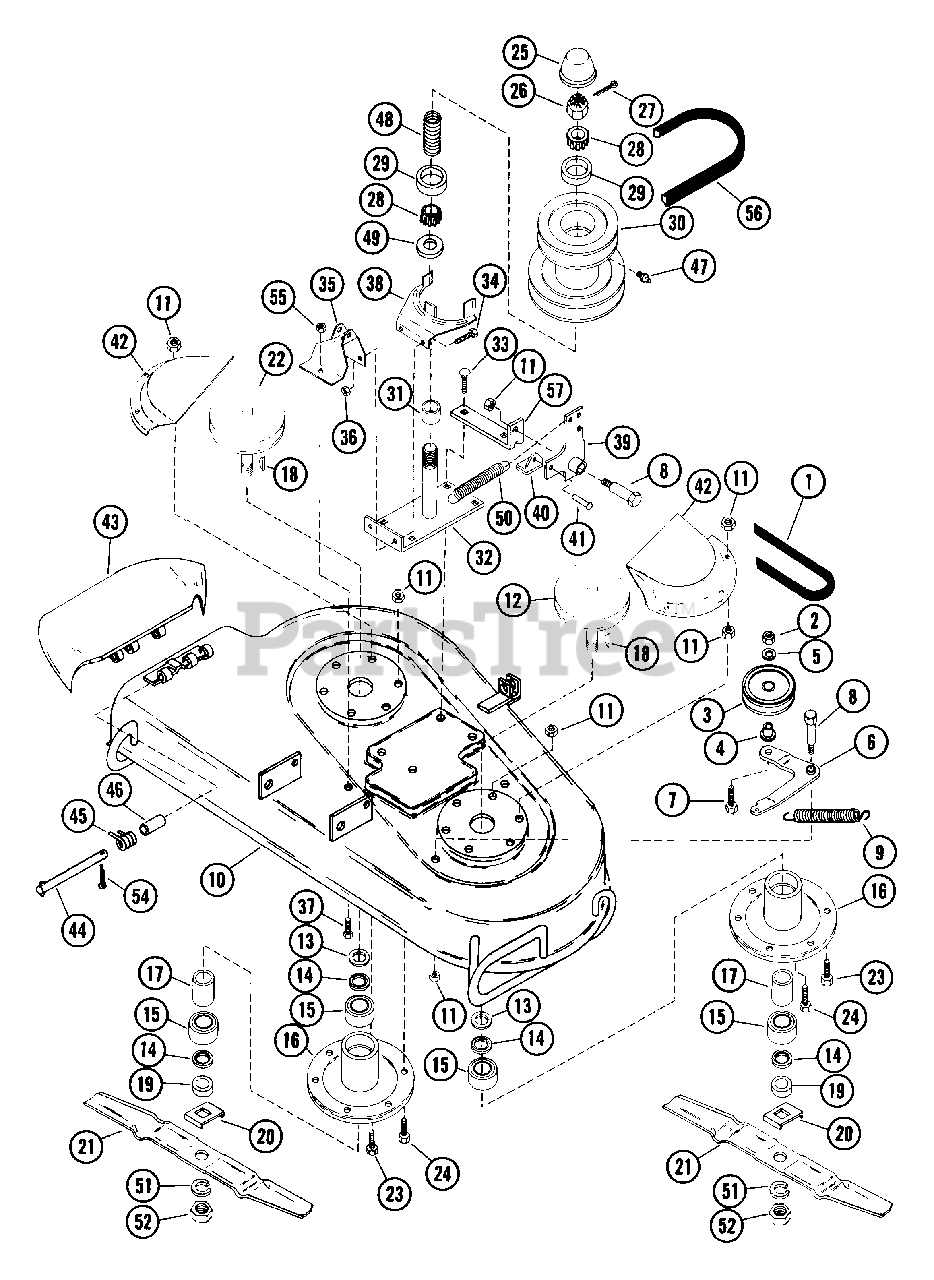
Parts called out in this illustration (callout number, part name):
1	V-BELT, 4L-RAW EDGE
2	NUT-LK-CTR .50-13
3	IDLER-FLAT 2.75X.62
4	BSHG-FLG .500X.625X.500X.750
5	WSHR-FL-STL .505X.880X.072 PL
7	BLT-HEX .50-13X1.25 PL GR2
8	SHOULDER BOLT
9	SG-TENS .091X.73X5.28 WLD 30
10	PAN ASSEMBLY
11	NUT-LK-CTR .375-16 GR A PL
13	WSHR-FL-STL .755X1.250X.125
14	BEARING SLINGER
15	BRG-BALL .751X1.78X.61
16	SPINDLE HOUSING
17	SPACER .753X1.000X1.140
18	KEY-WDRF .188X.75X.313 SAE 9
19	RETAINER HUB
20	BLADE TRAY
21	MOWER BLADE
22	SHEAVE
23	BLT-HEX .38-16X1.00 PL
24	BLT-HEX .38-16X.75 PL GR2
25	CAP, GREASE
26	NUT-JAM SL .75-20 PL
27	PIN-COTR .12 X 1.25 PL
28	BRG-CONE .750X.61
29	BRG-CUP 1.781X.475
30	SHEAVE ASSEMBLY-MOWER
31	SPACER .753X1.000X.625
33	BLT-RDHDSQNK .38-16X.75 SHT PL
34	BLT-SERHFWH .31-18X.75 PL
35	BRACKET
36	NUT-FLG. .312-18 PL
37	BLT-HEX .31-18X.50 PL GR2
41	RVT .25X.50 RH ST
43	PAN CHUTE EXTENSION
44	CLEVIS PIN
45	SG-TORS .095X.50X 1.0
46	BSHG-SLV .334 X .502 X 1.437
47	SPIN DRIVE ZERK FITTING
48	SG-COMP .091X.950X2.062
49	SEAL .750X1.690X.153
50	SG-TENS .072X.50X8.0 WLD 25
51	WSHR-LK .750X.188 MED PL
52	NUT-JAM .75-10 PL
54	PIN-COTR .09X.75 PL
55	NUT-LK .312-18 GR A PL
56	V-BELT, 5L-RAW EDGE
57	BRACKET
